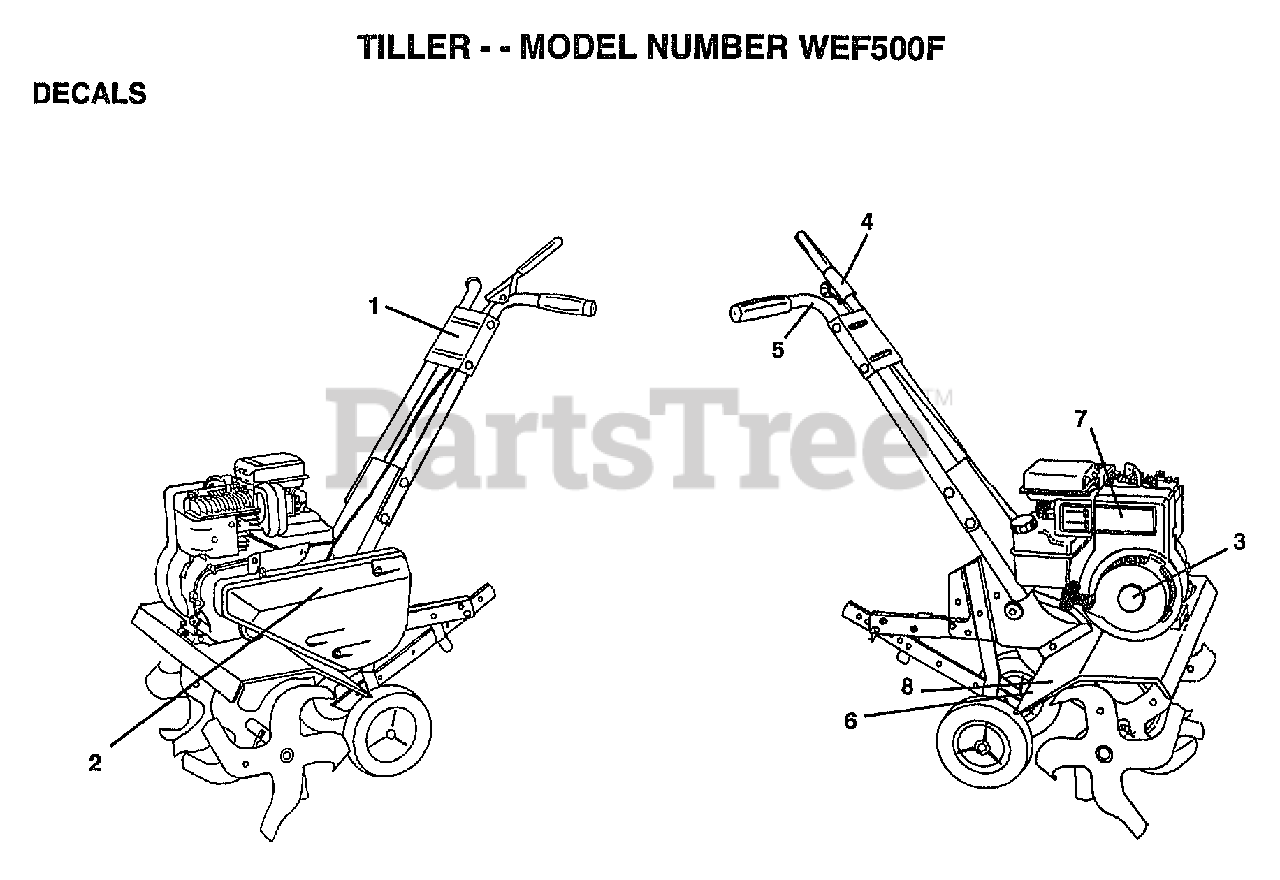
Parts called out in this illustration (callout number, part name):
1	DECAL.LOGO.CONTROL
4	DECAL TI
5	DECAL TI
6	DECAL.CAUTION
7	DECAL, BRIGGS & STRATTON
